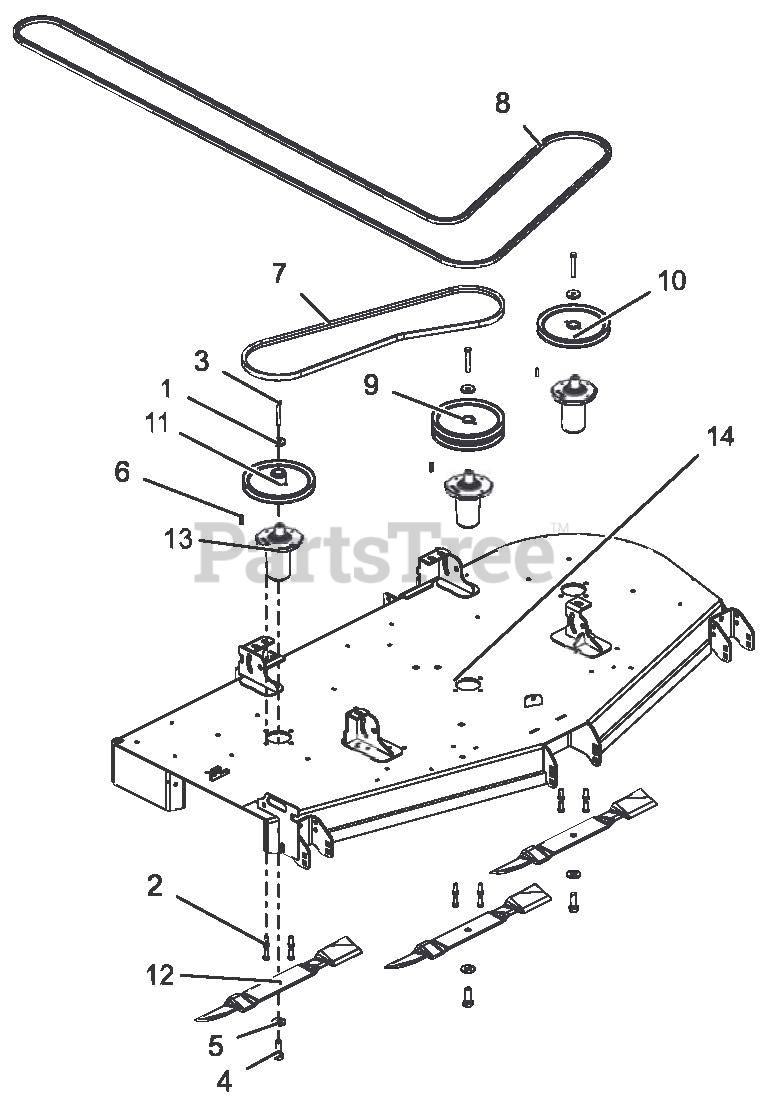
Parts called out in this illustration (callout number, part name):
1	RETAINER, SHEAVE SPINDLE
2	BLT-HEX .38-16 X 1.00 GR5 YWZC EP30
3	BLT-HEX .38-16 X 2.75 GR8 YWZC
4	BLT, HEX .62-18X1.75 GR8 YWZC
5	WSHR, BLVL .63X1.625X.14
6	KEY-SQ .250 X .250 X 1.00 RC 40-50
7	V-BELT, B-COGGED
8	HEX BELT, BB-WRAPPED-CLUTCHING
9	SHEAVE-DOUBLE 1.00"ID X 8.25"OD
10	SHEAVE-SINGLE 1.00" X 8.25" OD
11	SHEAVE, SINGLE 1.00" ID X 8.25" OD
12	BLADE, MOWER - 72", 24.50" LG
13	SERVICE, ASM SPINDLE- DUCTILE
14	72" SIDE DISCH DECK W/ SAFETY DECALS
